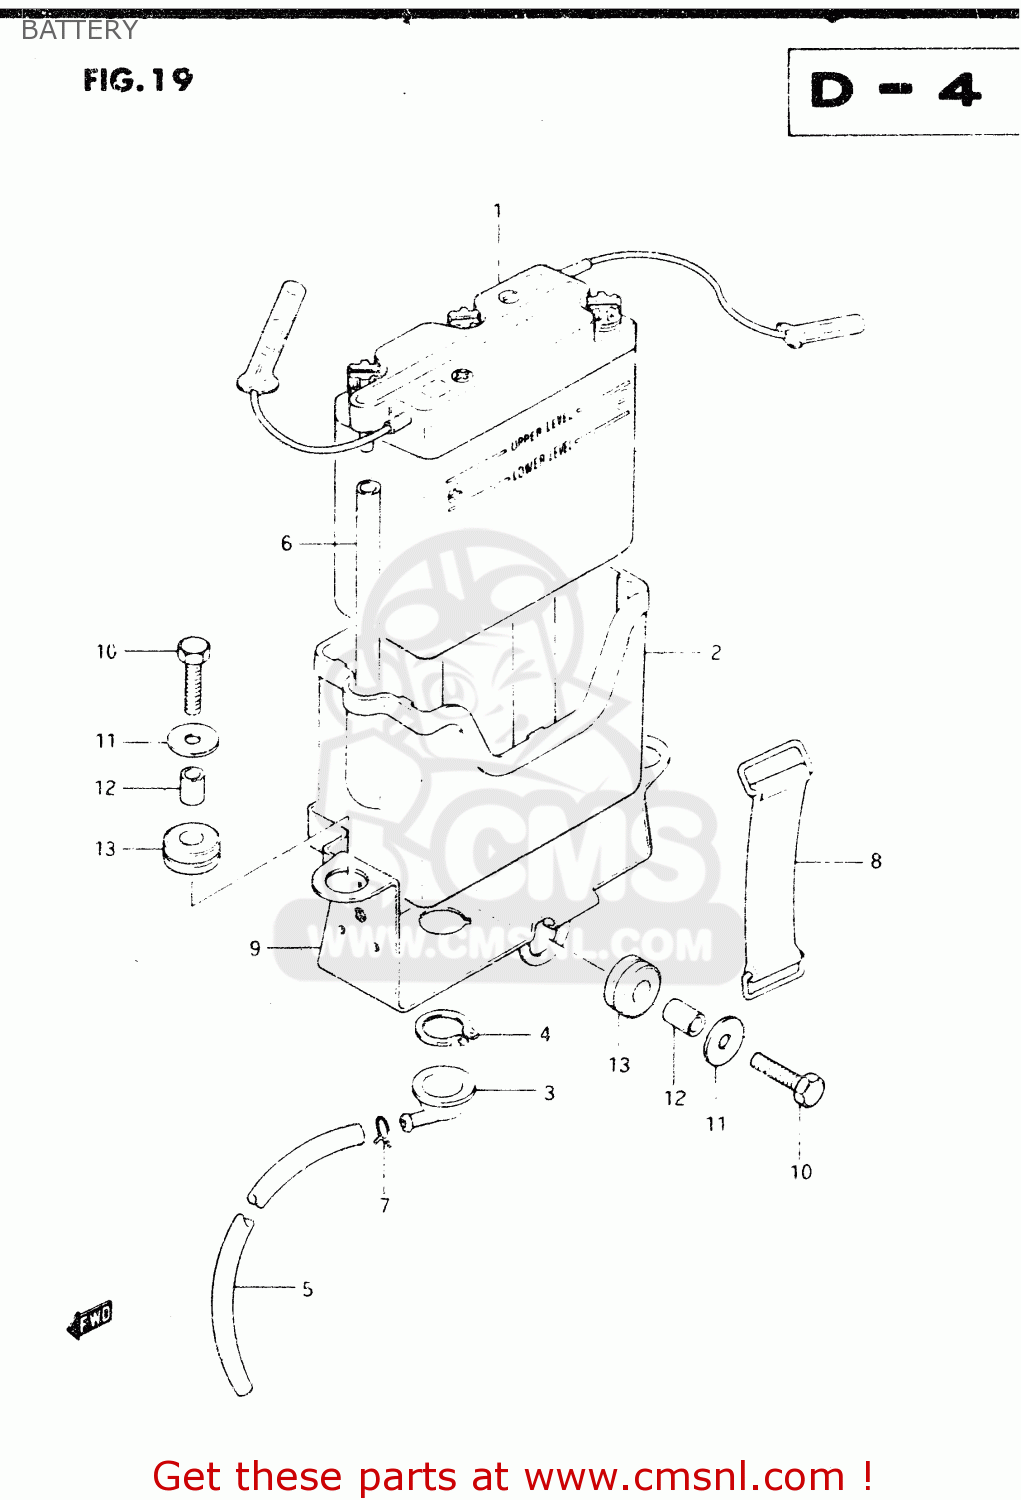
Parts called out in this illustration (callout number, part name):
1	BATTERY (6V, 4AH)
2	CASE,BATTERY
3	FUNNEL,BATTERY EXHAUST
4	CIRCLIP
5	HOSE,BATTERY EXHAUST
6	HOSE, EXHAUST (L:45)
7	CLIP
8	BAND
9	HOLDER,BATTERY
10	BOLT, UPPER
11	WASHER (6.5X20X1.2)
12	SPACER(6.1X9X7.5)
13	CUSHION
